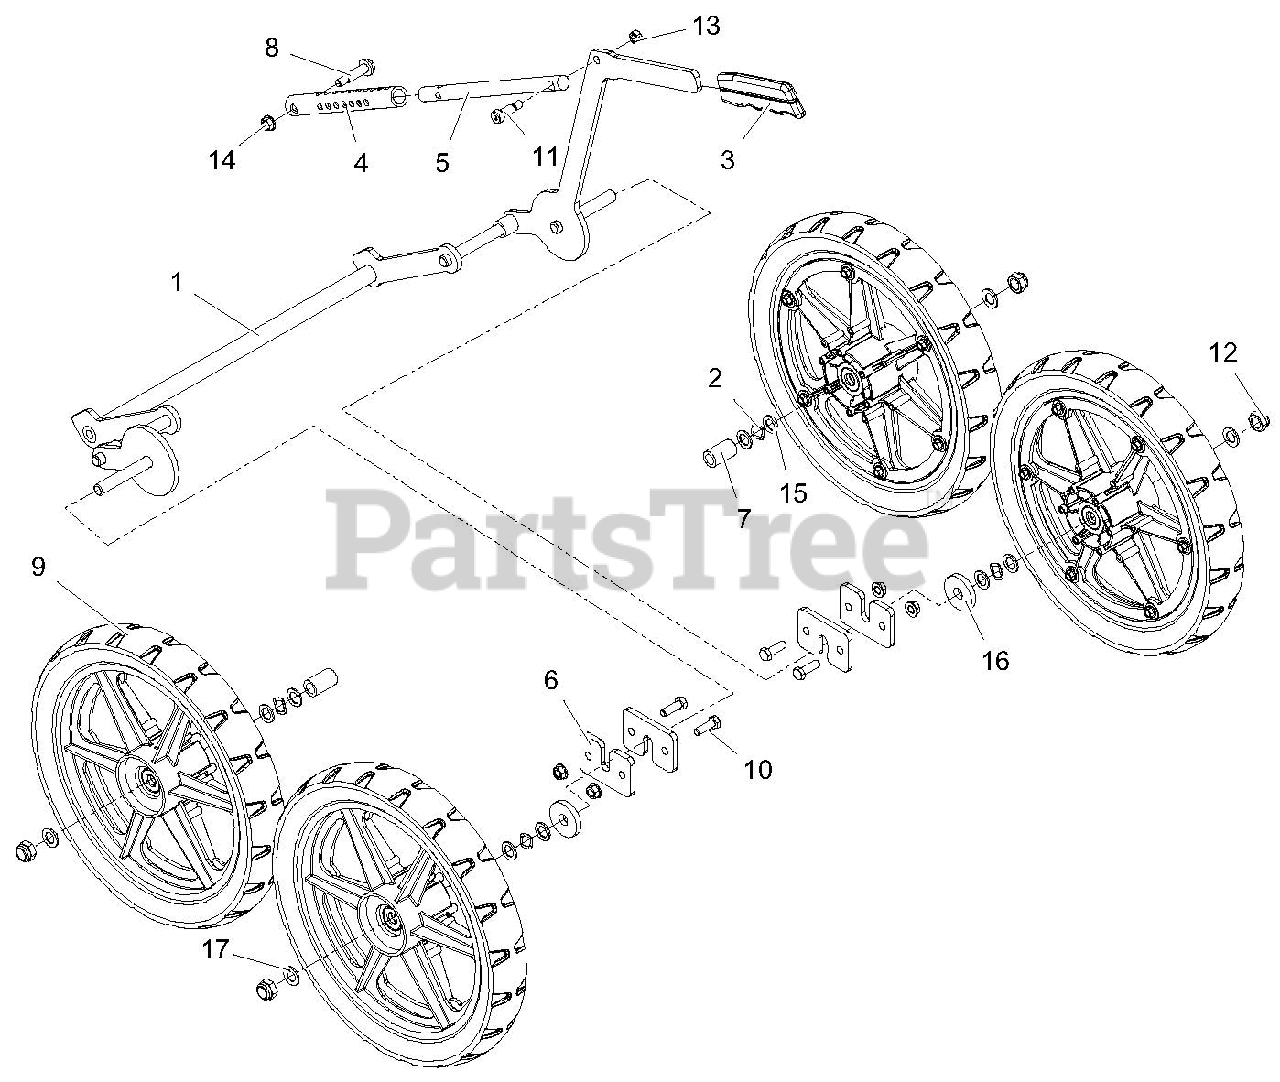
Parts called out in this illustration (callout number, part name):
1	WLDMT, AXLE - APV HEIGHT ADJ SYS
2	WAVE WASHER .531 x .781 x .125 FH
3	GRIP, PARKING BRAKE (YELLOW)
4	TUBE, ADJ - APV HEIGHT ADJ
5	ROD, ADJ - APV HEIGHT ADJ
6	PLATE, RETAINER - APV HEIGHT ADJ
7	SPCR, WHEEL - APV REAR WHEEL
8	BLT, SHLDR .50 x 1.30 x .38-16 GR5
9	ASM, WHEEL 14 x 2 .50ID W/DRIVE HUB
10	BLT-HEX .31-18 x 1.00 GR5 YWZC
11	BLT-SHLDR .375 x .750 x .31-18 ZC
12	NUT, ACORN .500-13 LC YWZC
13	NUT-LK-CTR .31-18 YWZC
14	NUT, LK-TOP-FLG .312-18 YWZC
15	WSHR-FL-STL .520 x .827 x .062 YWZC
16	WSHR-FL-STL .515 x 1.625 x .250 YWZC
17	WSHR-FL-STL .505 x .880 x .072 YWZC
